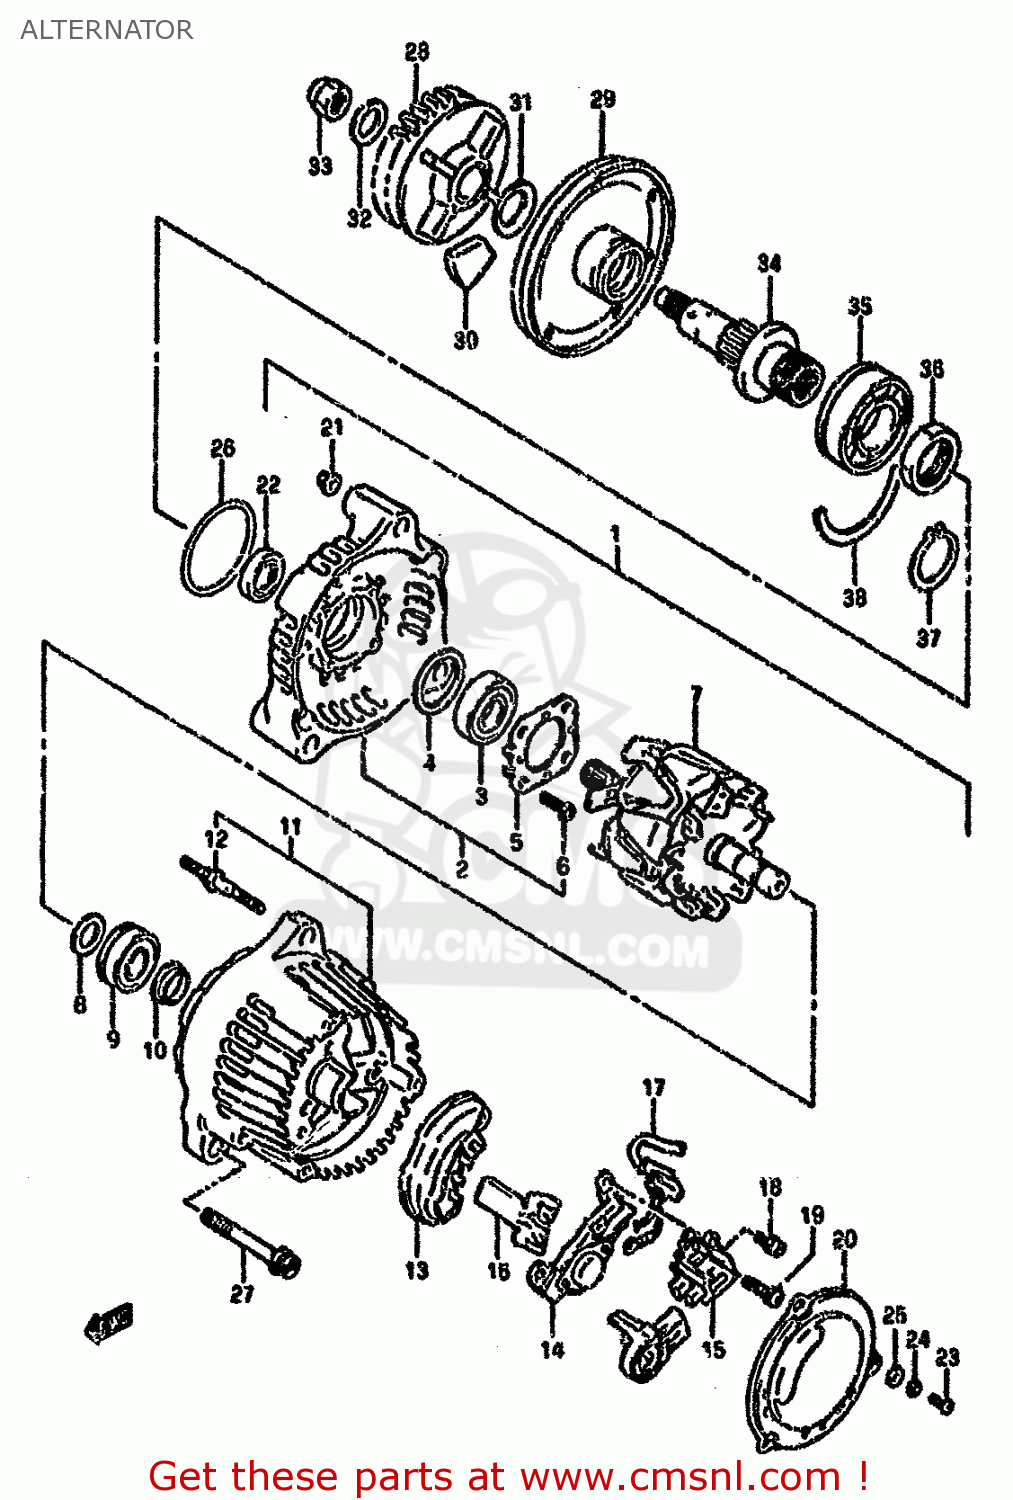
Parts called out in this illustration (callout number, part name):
1	ALTERNATOR ASSEMBLY
2	FRAME,DRIVE END
3	BEARING
4	COVER,BEARING
5	RETAINER,BEARING
6	SCREW,BEARING RETAINER
7	ROTOR ASSEMBLY
8	COVER,BEARING
9	BEARING
10	COVER(2)
11	FRAME,END
12	STUD BOLT
13	HOLDER,RECTIFIER
14	REGULATOR
15	HOLDER,BRUSH
16	COVER,RECTIFIER
17	WIRE,LEAD
18	SCREW
19	SCREW
20	COVER
21	NUT
22	OIL SEAL SET
23	SCREW
24	WASHER,LOCK
25	WASHER,5MM
26	O RING
27	BOLT
28	GEAR,GENERATOR DRIVEN
29	HOUSING,GENERATOR DAMPER
30	DAMPER,GENERATOR
31	WASHER
32	WASHER
33	NUT
34	SHAFT,GENERATOR DRIVE
35	BEARING(25X52X15)
36	NUT
37	CIRCLIP
38	C RING
